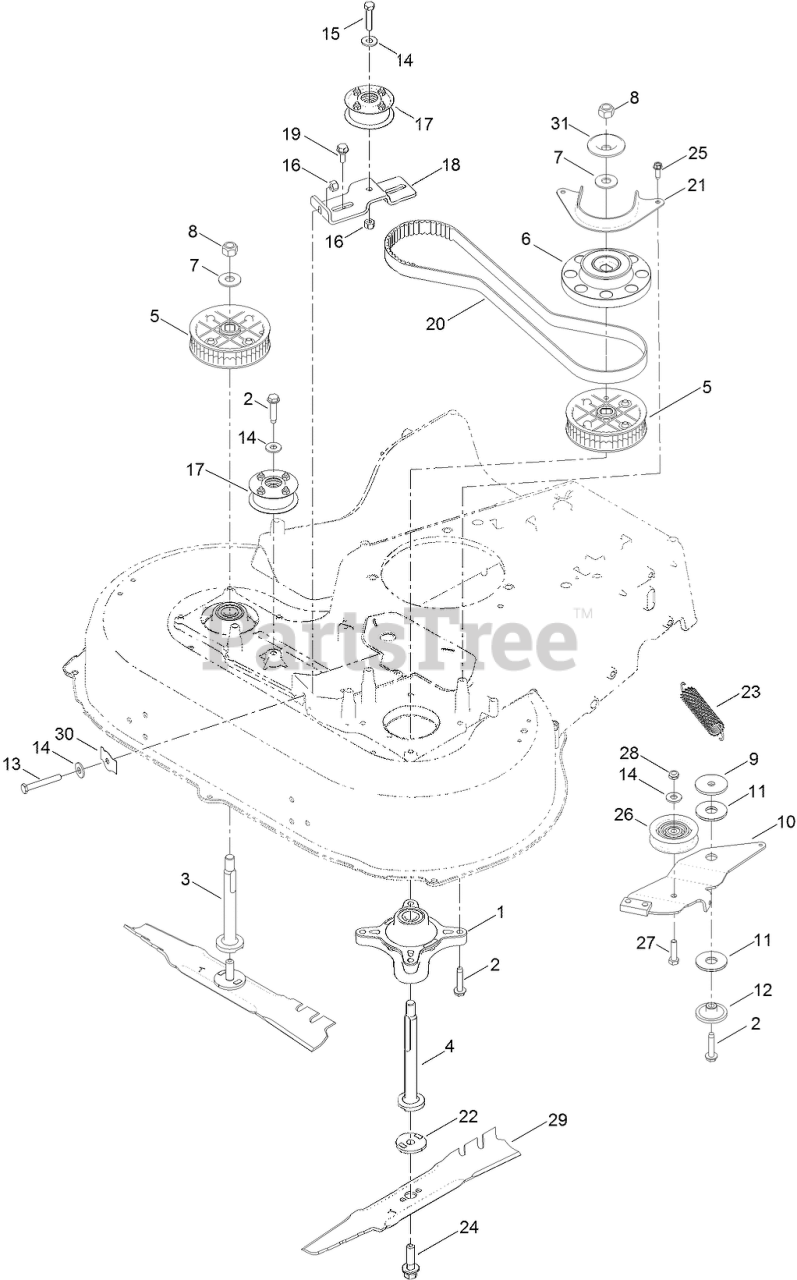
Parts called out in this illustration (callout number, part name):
1	SPINDLE ASM
3	SHAFT-SPINDLE
4	SHAFT-SPINDLE
5	SPROCKET
6	PULLEY-BRAKE, SPINDLE
7	WASHER-SPRING
8	NUT-HEX
9	WASHER-REBOUND
10	ARM-BRAKE
11	WASHER-FRICTION, COMPOSITE
12	SPACER
13	BOLT-TAP, HH
14	WASHER-FLAT
15	SCREW-HH
16	NUT-LOCK, NI
17	PULLEY ASM
18	BRACKET-IDLER
19	SCREW-SHOULDER, HHF
20	BELT-SYNCHRONOUS
21	GUIDE-BELT, SPINDLE
22	ADAPTER-BLADE
23	SPRING-EXTENSION, BRAKE
24	BOLT-BLADE
25	SCREW-HWHTF
26	PULLEY-IDLER
27	SCREW-HH
28	NUT-LOCK, NI
29	BLADE-ROTARY
30	SPRING-FLAT
31	WASHER-CUP
